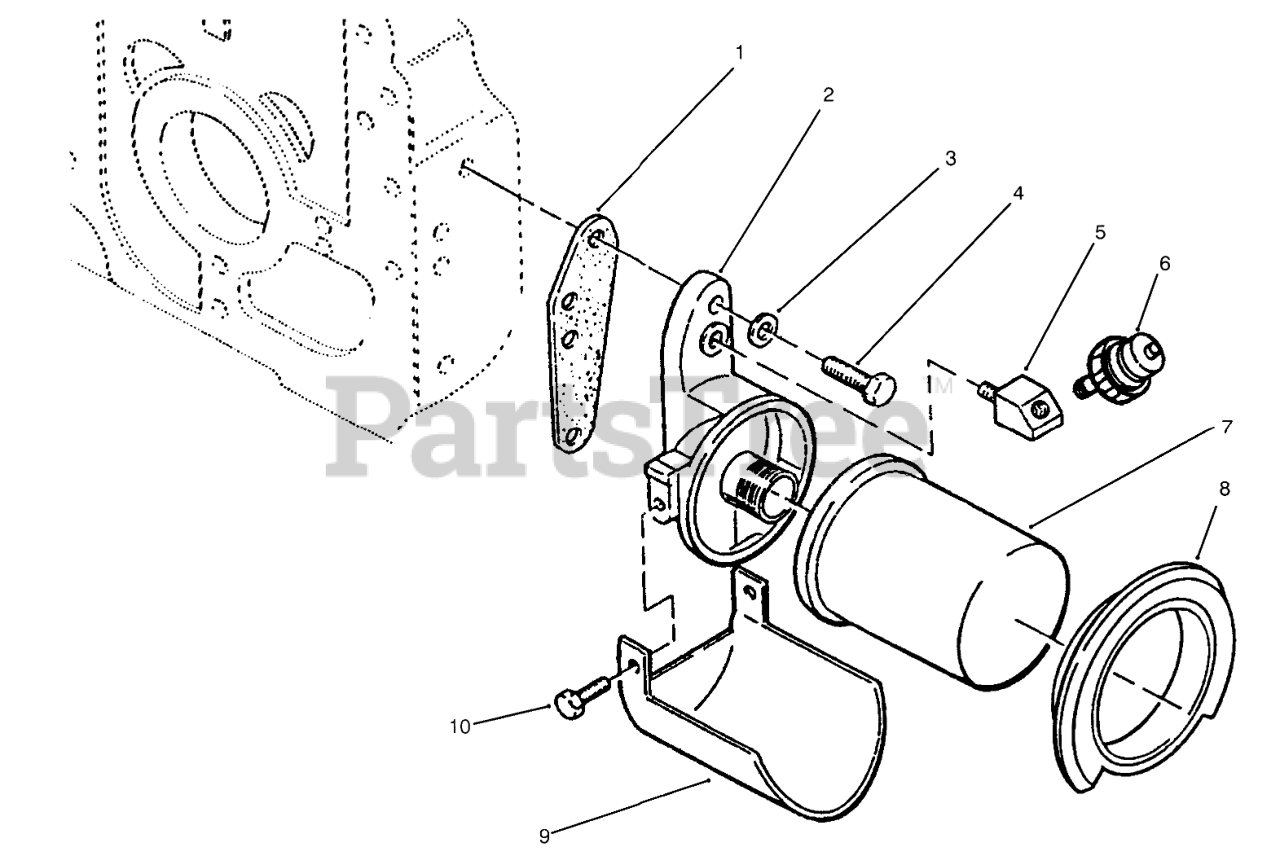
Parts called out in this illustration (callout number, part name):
1	Gasket
2	ADAPTER-OIL FILTER
3	WASHER
4	HHCS 5/16-18 X 1
5	45 DEG STREET ELBOW
6	SWITCH
7	OIL FILTER
8	GASKET - AIR SEAL
9	OIL-FILTER DRAIN
10	SCREW-HH
